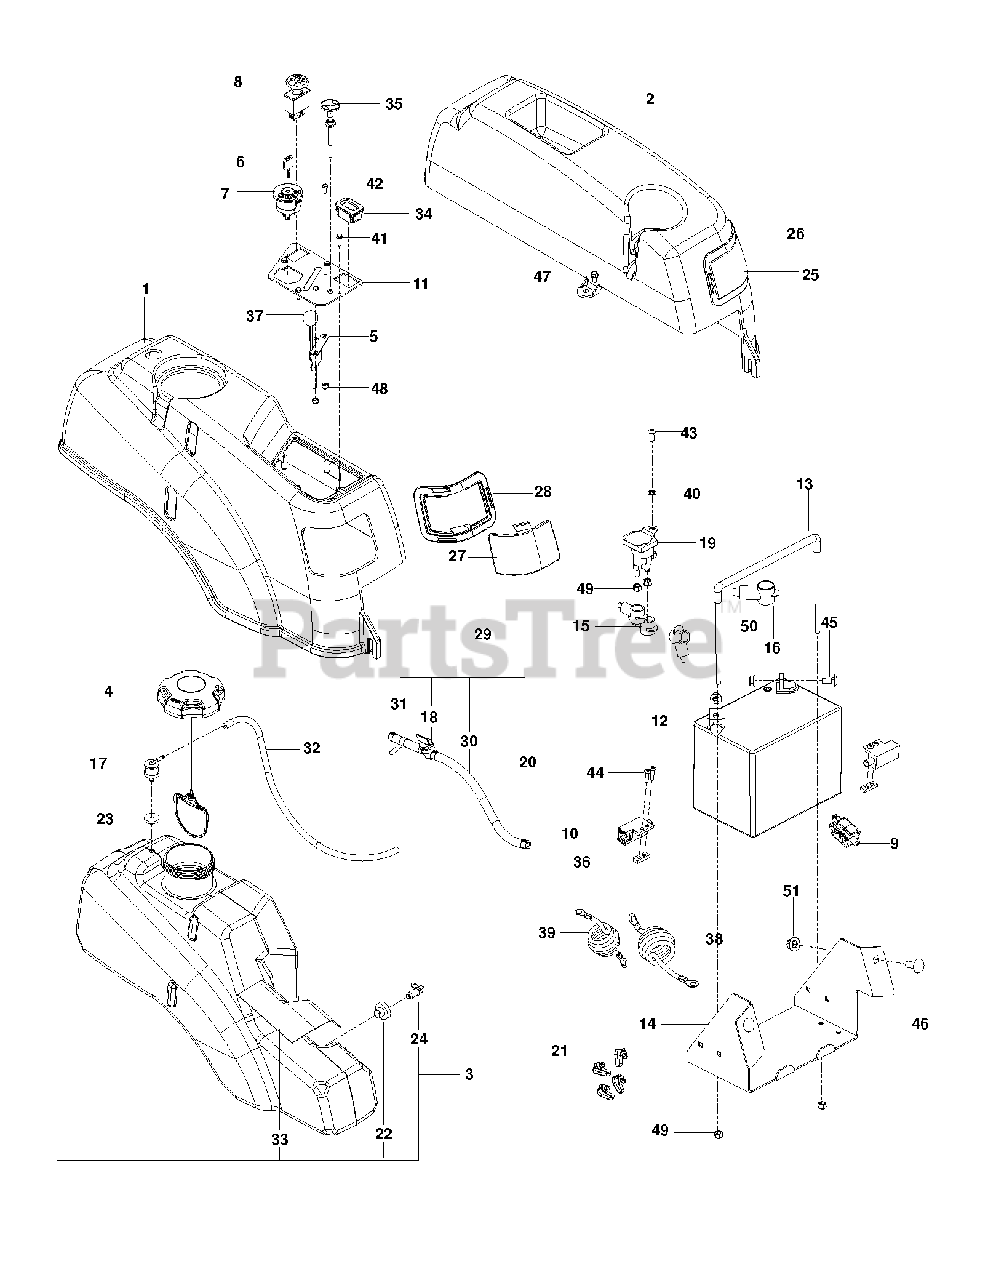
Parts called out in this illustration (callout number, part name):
1	FENDER RT, BLACK
2	FENDER, LT, BLK
3	FUEL TANK ASM, LARGE
4	CAP, FUEL
5	THROTTLE CABLE
7	IGNITION SWITCH
9	SWITCH, BRAKE 3P
13	BATTERY TIE DOWN ASSEMBLY
14	BOX, BATTERY, BLACK
15	TERMINAL COVER-SM
16	INSULATOR
17	VALVE.FUEL.CHECK
18	FUEL VALVE
19	SOLENOID.W/BRASS.PLUNG
20	HOSE CLAMP
21	TIE WRAP, 8-3/8", W/CLIP
22	RUBBER GROMMET
23	GROMMET, CHECK VALVE
25	PANEL, LT
26	RING, LT BLK
27	PANEL, RT, BLK
28	RING, TRIM, RT-BLK
29	FUEL LINE ASSY
30	GAS LINE 10"
31	FUEL LINE 2.5"
32	HOSE, FUEL, 3/16" X 20"
35	CHOKE CABLE
36	TAPPED PLATE
37	KNOB ROUND BALL
38	CABLE POSITIVE, LONG
39	BATTERY CABLE, NEGATIVE
40	WASHER 1/4 INT TOOTH
41	SCR #10-12X3/4 HEX WAS HD ZD
42	HCS #10-24 X 1/2
43	SCR 1/4-20 X 5/8 BTN SKT HD ZD
44	SCR #10-24 X .75 SKT HD BLK
45	BOLT 5/16C X 3/4" CARRIAGE
46	RHSNB 3/8C X 1
47	BOLT 1/4-20 X 1/2 HWST
48	NUT 10-24 NYLOC
49	NUT 1/4-20 NYLOC
50	5/16-18 NYLOC FLANGE NUT
51	NUT 3/8-16 HEX FLG NYLOC ZD
